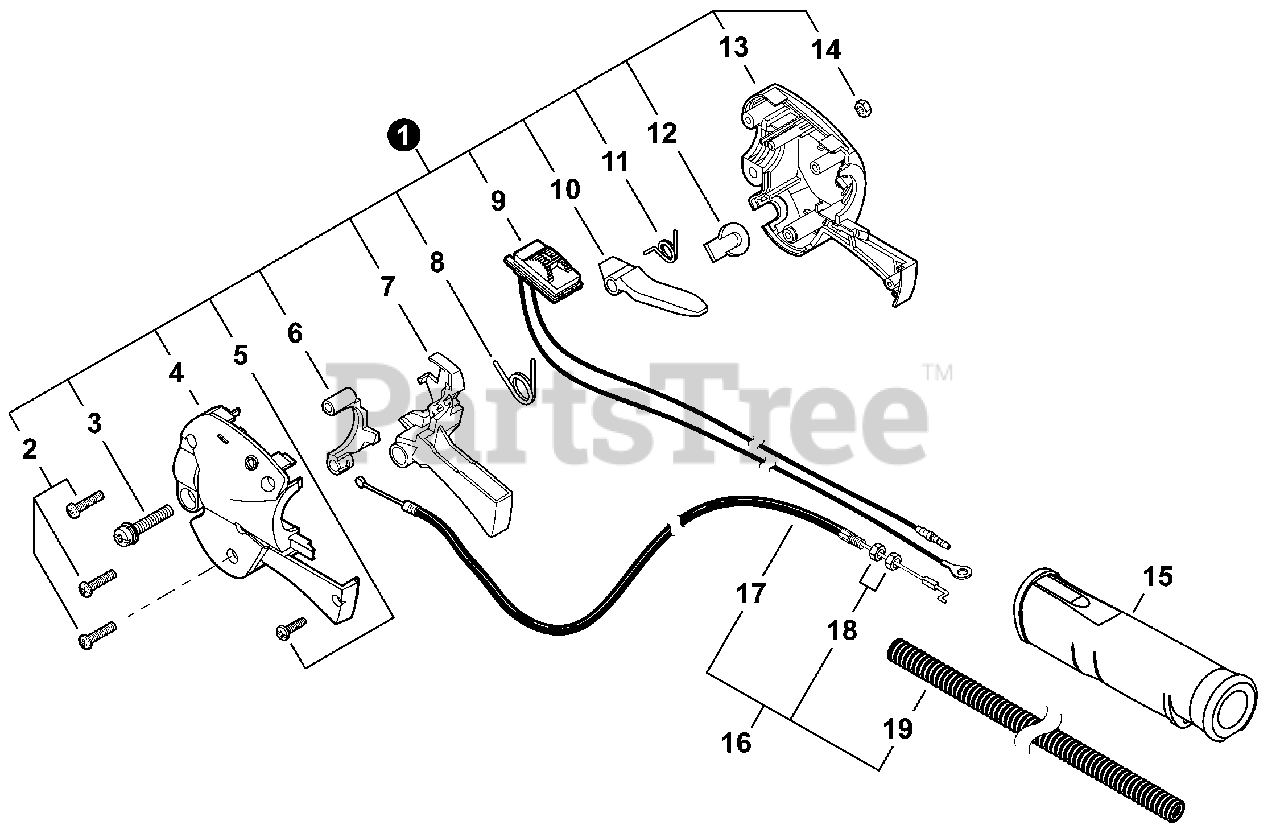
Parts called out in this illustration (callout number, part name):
1	THROTTLE CONTROL ASSY
2	SCREW, TAPPING M4×20
3	SCREW M5×20
4	CONTROL HANDLE - LEFT
5	SCREW, TAPPING 3×14
6	LOCKOUT, THROTTLE
7	TRIGGER, THROTTLE
8	SPRING, THROTTLE RETURN
9	SWITCH, ON-OFF
10	LEVER, THROTTLE LOCKOUT
11	SPRING, THROTTLE LOCKOUT
13	CONTROL HANDLE - RIGHT
15	GRIP, REAR
16	CABLE ASSY, THROTTLE
17	CABLE, THROTTLE
19	TUBE, PLASTIC PROTECTIVE
